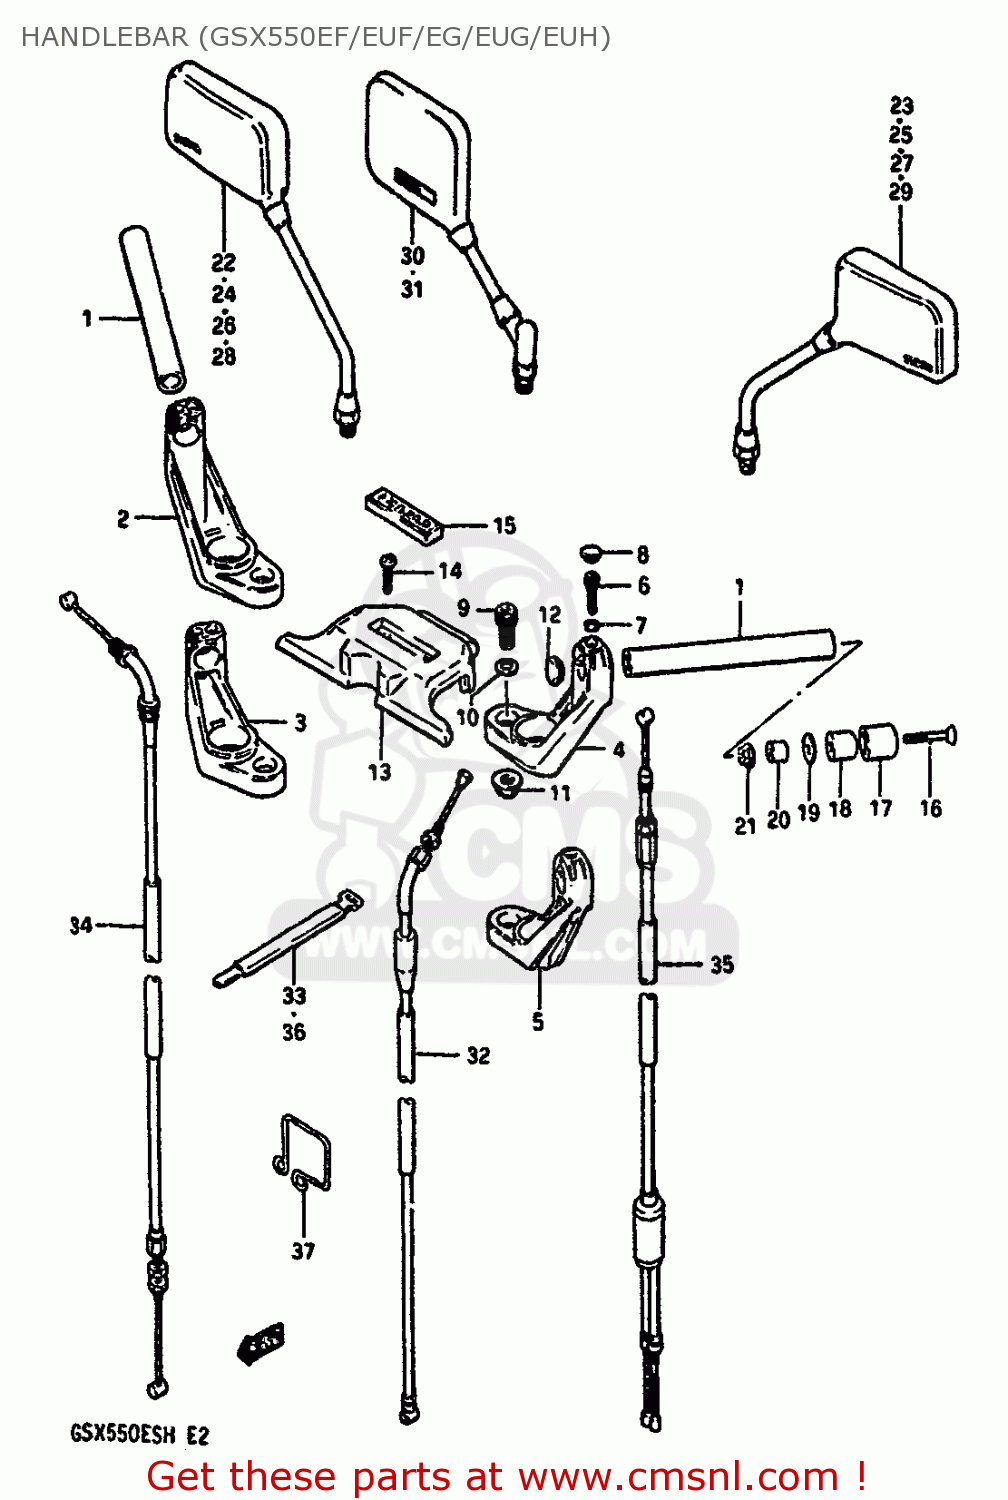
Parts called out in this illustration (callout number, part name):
1	HANDLEBAR
2	HOLDER,HANDLEBAR,RIGHT
3	HOLDER,HANDLEBAR,RIGHT
4	HOLDER,HANDLEBAR,LEFT
5	HOLDER,HANDLEBAR,LEFT
6	BOLT 8X35
7	WASHER
8	CAP(OD:14.5)
9	BOLT(10X50)
10	WASHER
11	NUT
12	CAP,GRIP END
13	PAD,HANDLEBAR
14	SCREW
15	EMBLEM,HANDLE PAD
16	SCREW 6X55
17	CAP,BALANCER
18	BALANCER,HANDLEBAR
19	SPACER,BALANCER
20	EXPANDER,BALANCER
21	NUT
22	MIRROR ASSEMBLY,REAR VIEW
23	MIRROR ASSEMBLY,REAR VIEW
24	MIRROR, REAR VIEW RH
25	MIRROR, REAR VIEW LH
26	MIRROR,REAR VIEW RH
27	MIRROR,REAR VIEW LH
28	MIRROR,REAR VIEW RH
29	MIRROR,REAR VIEW LH
30	MIRROR ASSEMBLY,REAR VIEW
31	MIRROR ASSEMBLY,REAR VIEW
32	CABLE ASSY,CLUTCH
33	CLAMP
34	CABLE ASSY,THROTTLE
35	CABLE COMP,STARTER
36	CLAMP
37	GUIDE,CABLE/HARNESS
